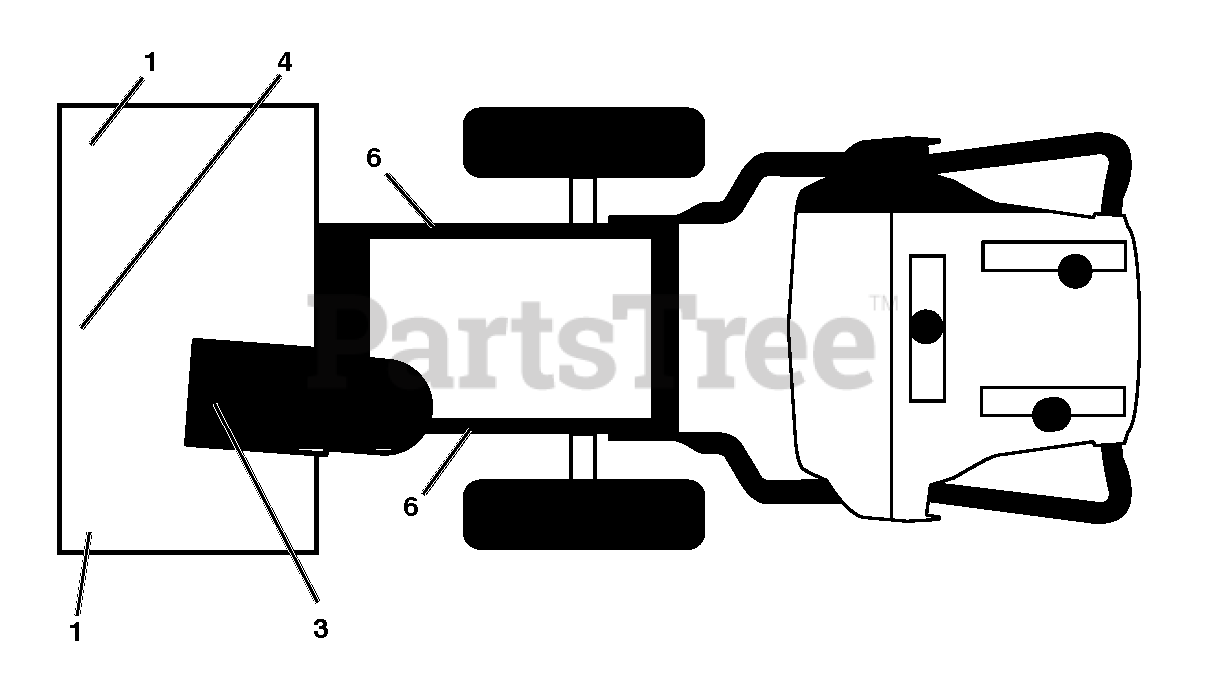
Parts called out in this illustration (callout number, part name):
1	DECAL.AUGER.SAFETY.
3	DECAL.CHUTE.SAFETY.
4	DECAL.AUGER."
6	DECAL.FENDER
